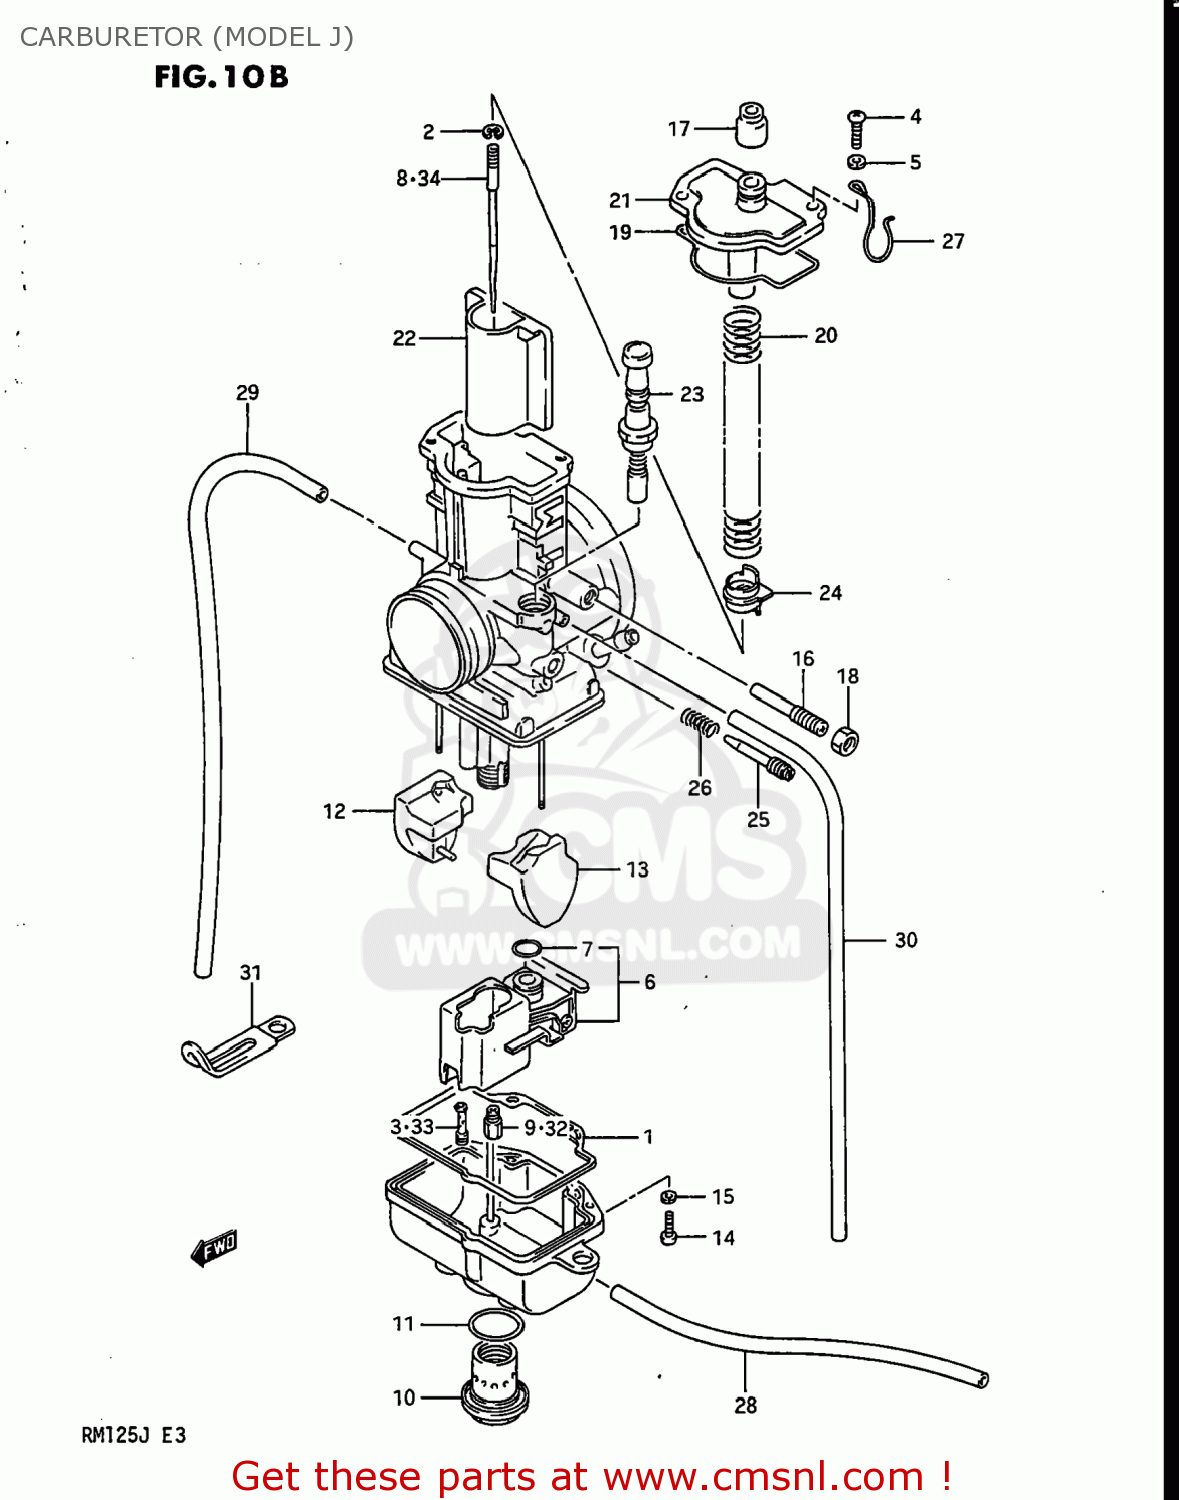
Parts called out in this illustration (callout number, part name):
1	O RING,FLOAT CHAMBER
2	CLIP,NEEDLE
3	JET,PILOT 20
4	SCREW
5	LOCK WASHER
6	VALVE ASSY,NEEDLE
7	O-RING,NEEDLE VALVE
8	NEEDLE JET
9	JET,MAIN(350)
10	CAP,DRAIN
11	O RING,DRAIN PLUG
12	FLOAT,R
13	FLOAT,L
14	SCREW
15	LOCK WASHER
16	ADJUSTER
17	CAP
18	NUT
19	O RING,TOP CAP
20	SPRING
21	CAP,TOP
22	VALVE
23	PLUNGER ASSY
24	RING
25	SCREW,AIR
26	SPRING
27	CLIP
28	HOSE
29	HOSE
30	HOSE
31	CLAMP
32	JET,MAIN(310)
33	JET,PILOT(15)
34	NEEDLE JET
